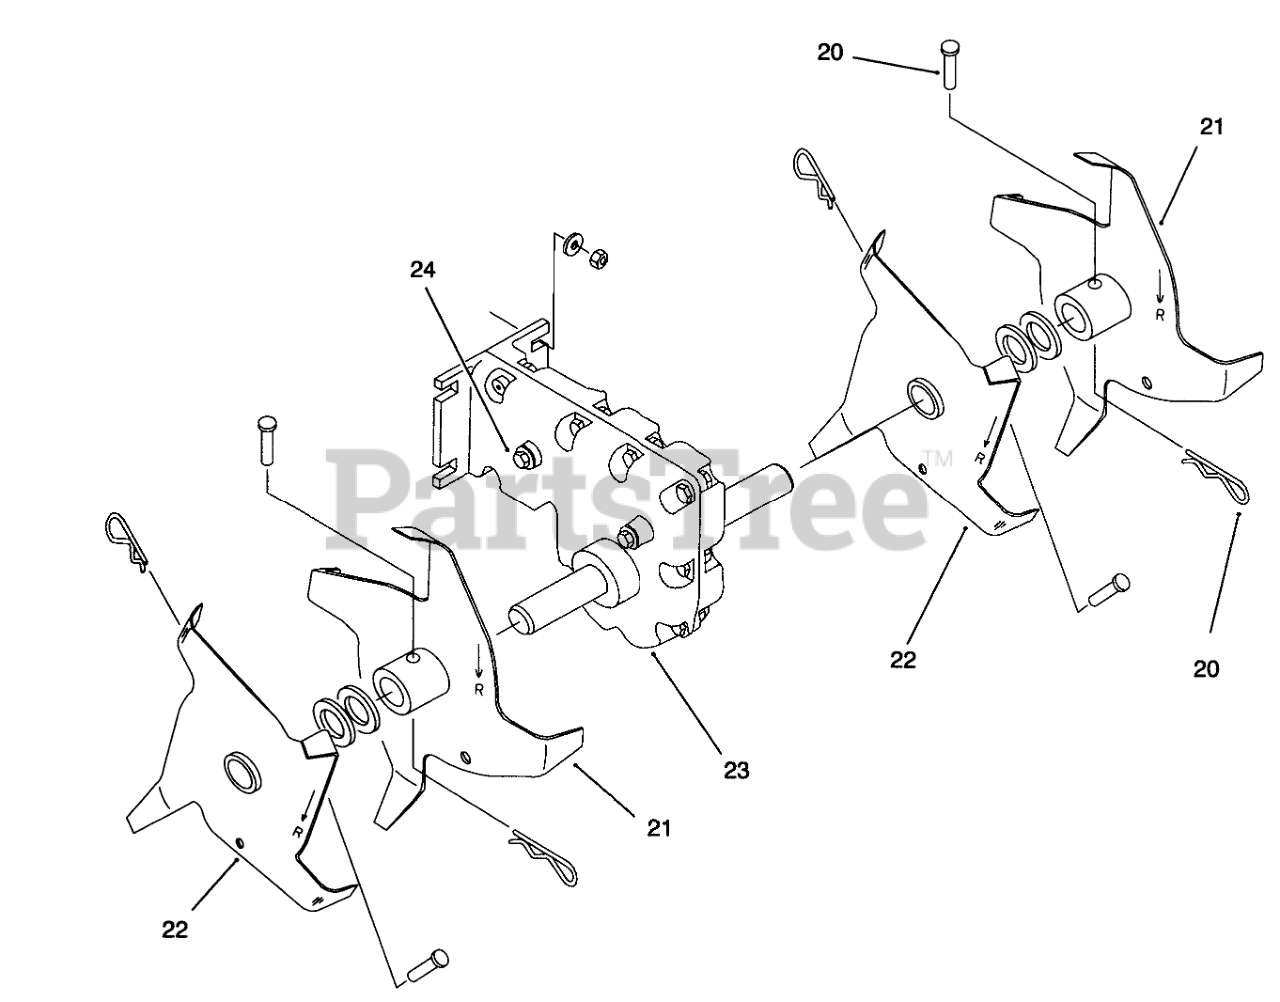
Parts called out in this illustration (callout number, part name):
20	ASSEMBLY - TINE FASTENER
21	ASSEMBLY - TINE
22	ASSEMBLY - TINE
23	ASSEMBLY - GEAR BOX
24	ASM-RETAINER BOLT SLEEVE
